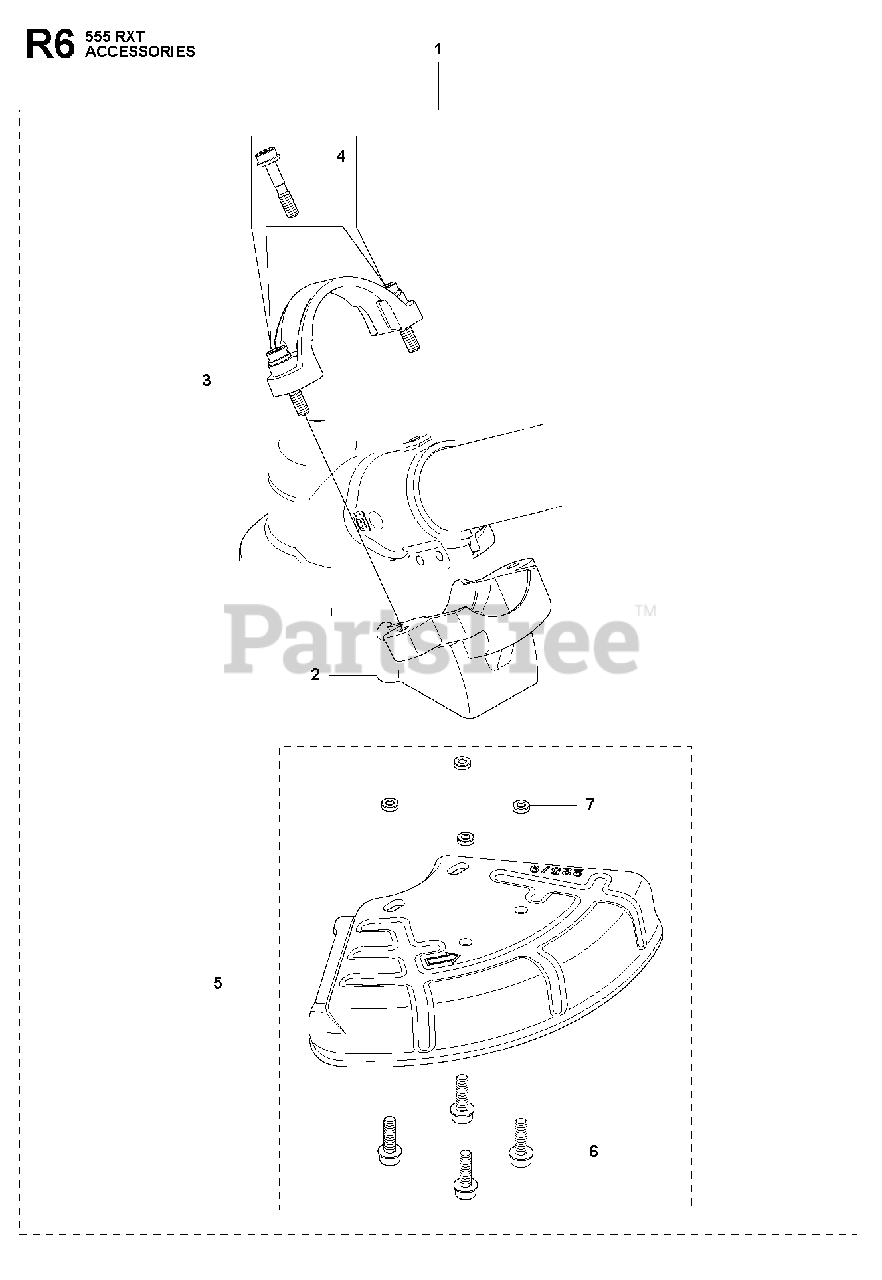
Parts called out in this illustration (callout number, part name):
1	ADAPTER
2	ADAPTER
4	SCREW IHSCFMO
5	BLADE GUARD
6	SCREW
7	LOCKING NUT
